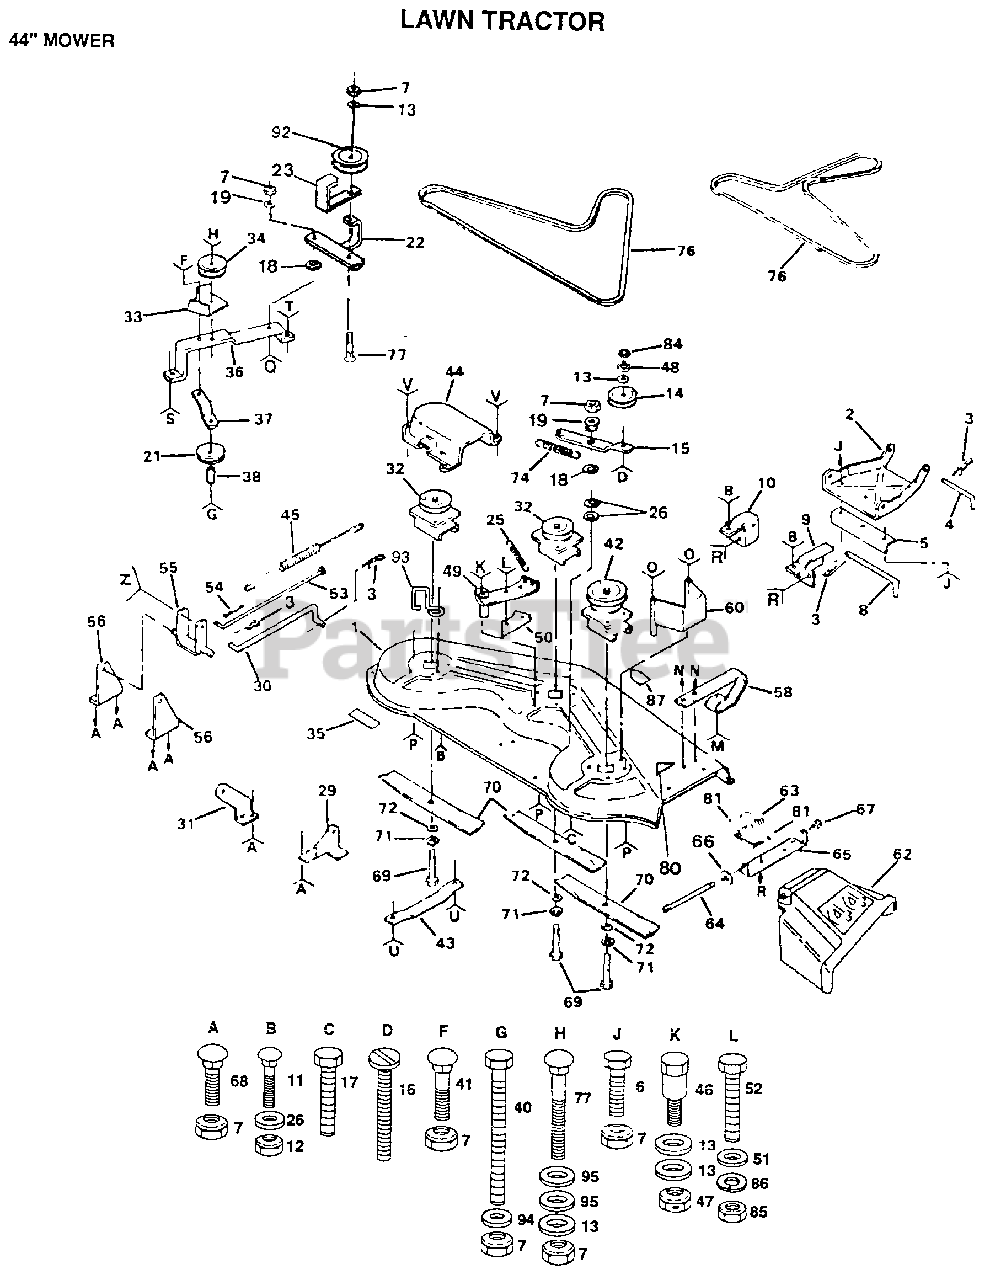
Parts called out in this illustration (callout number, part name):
2	LINK.PARALLEL
3	SPRING.RETAINER
4	"ROD, FRT. PARAL T"
5	LINK STOP
8	HINGE PIN T
9	BRACKET RH YT
10	BRACKET LH YT
11	BOLT
13	WASHER
14	IDLER.FLAT.GTV
15	ARM-IDLER YT
16	SCREW YT
18	"WASHER, WEAR LT"
19	SPACER RETAINER
21	IDLER-FLAT T
23	GUIDE BELT
25	SPRING-EXT YT
26	WASHER M
29	BRKT SUSP REAR RH
31	BRKT SUSP REAR LH
33	GUIDE-BELT YT
34	IDLER-INSIDE T
36	"SUPPORT YT, BAR"
37	BRACE-IDLER YT
38	SPACER
40	BOLT - HEX 3/8 - 16 X 3
43	RUNNER-LH M
44	GUARD YT
46	BOLT SHOULDER
47	LOCKNUT
48	LOCKWASHER
49	BRAKE ARM LT
50	BRAKE-BLOCK YTV
51	WASHER
53	ROD BRAKE YT
56	SUPPORT SHAFT YT
62	DEFLECTOR SHIELD
64	ROD-HINGE T
66	WASHER
67	NUT PUSH M
68	BOLT
69	BOLT.3/8-24X1-1/2
72	WASHER
76	BELT-V.79.1.MWR
77	BOLT
81	CAP-SLEEVE LT
84	NUT.HEX.3/8-16UNC
85	NUT.HEX.5/16-18
86	LOCKWASHER
87	DECAL WARNING
92	PULLEY IDLER
93	BELT RETIANER
94	WASHER
95	WASHER
